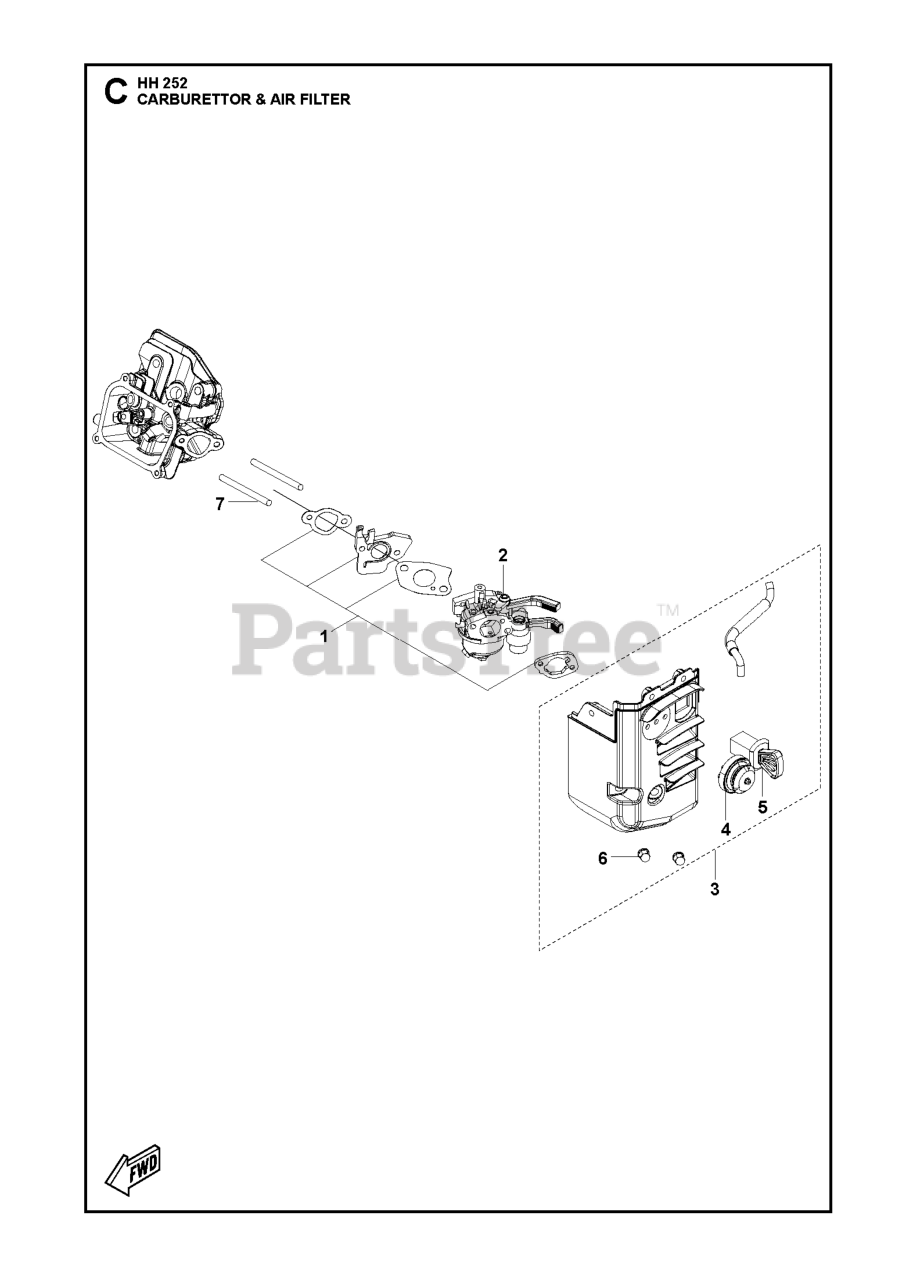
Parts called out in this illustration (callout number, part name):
1	GASKET KIT CARBURETTOR GASKET
2	CARBURETTOR
3	AIR FILTER ASSY
4	VALVE STARTING RICHED VALVE
5	SWITCH STOP ENGINE SWITCH
